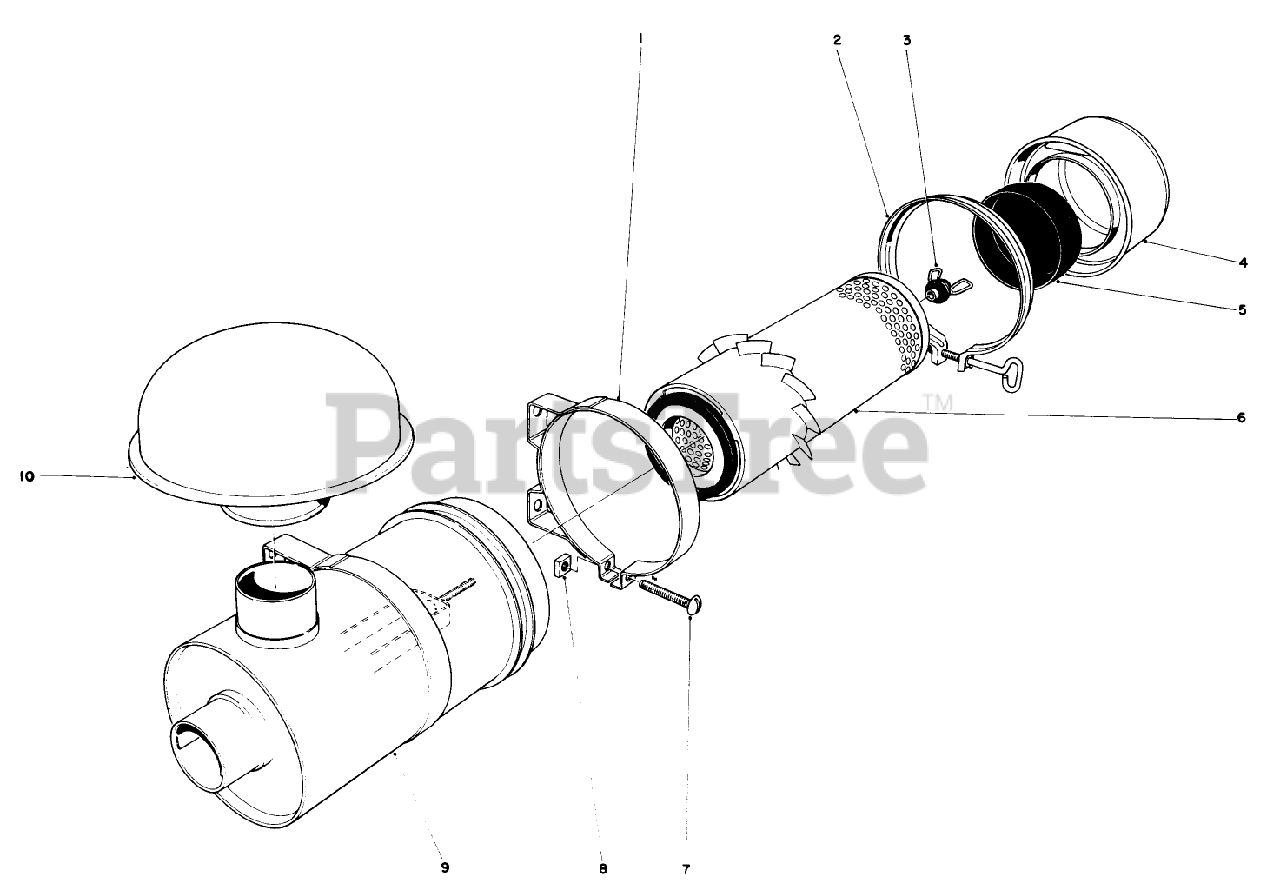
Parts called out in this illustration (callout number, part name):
1	MTG BAND ASM
2	CLAMP ASM
3	NUT ASM
4	CUP ASM
5	BAFFLE
6	ELEMENT ASM
7	SCREW
8	NUT-SQUARE
9	Body Assembly
10	HOOD-INLET, AIR
